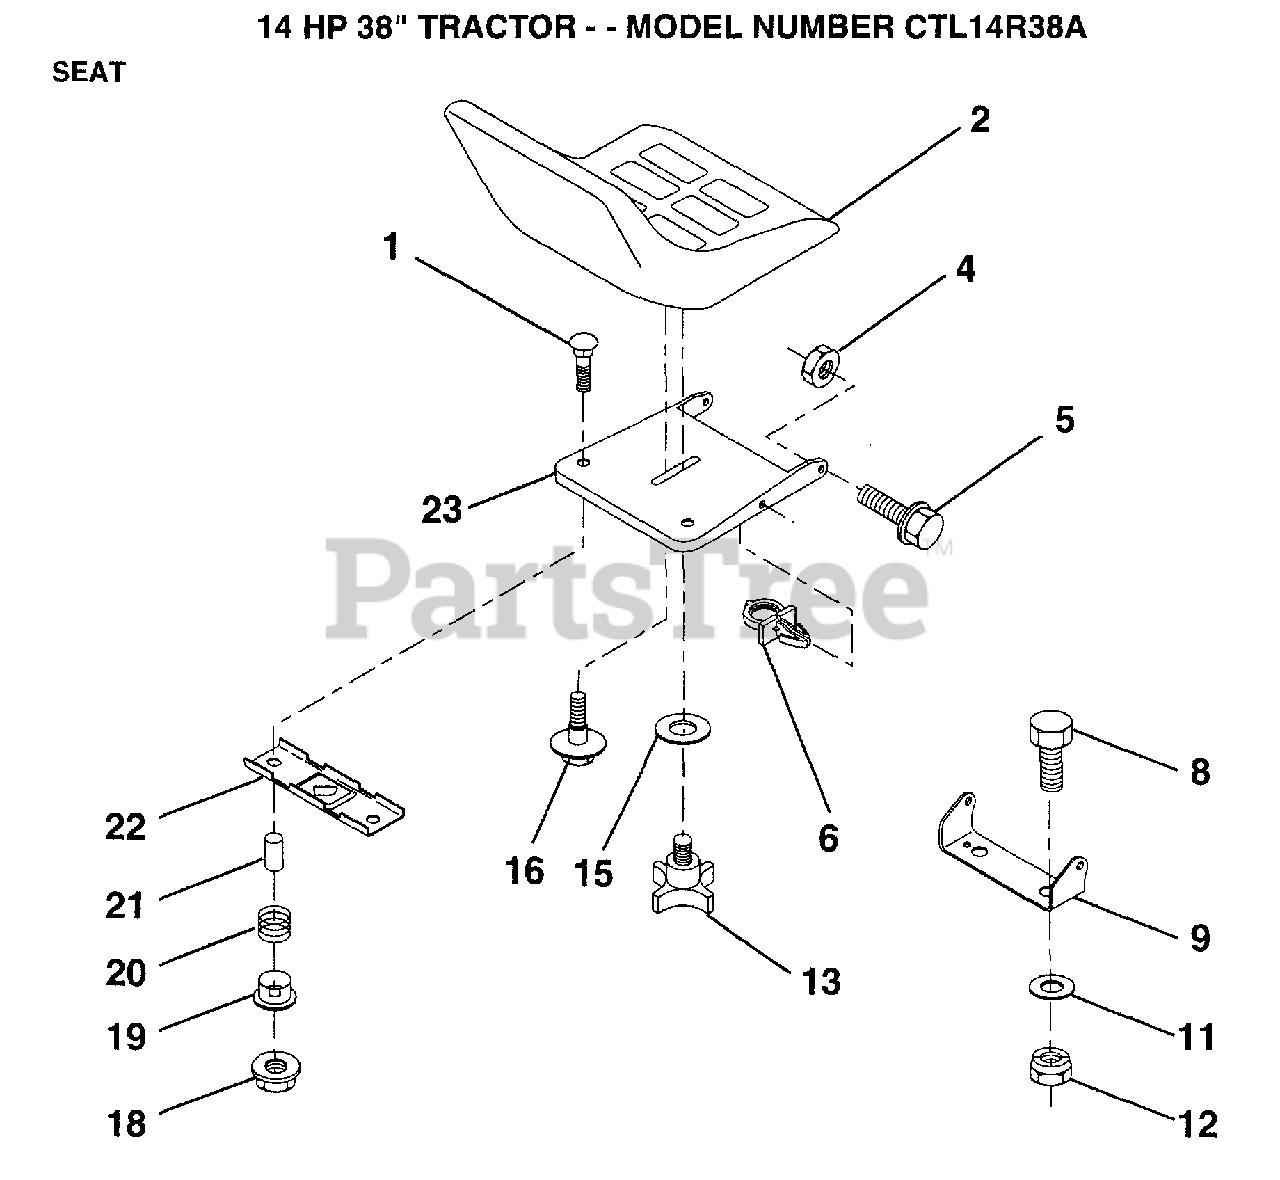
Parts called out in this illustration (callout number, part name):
4	NUT
5	BOLT.SHLD.5/16-18
6	CLIP PUSH - IN
8	BOLT
9	BRACKET PVT SEAT
11	WASHER
12	NUT
13	"KNOB 1/2"" YT"
15	WASHER
16	"BOLT,SHOULDER"
19	BUSHING
20	SPRING
21	SPLIT SPACER
22	BRKT SWITCH
